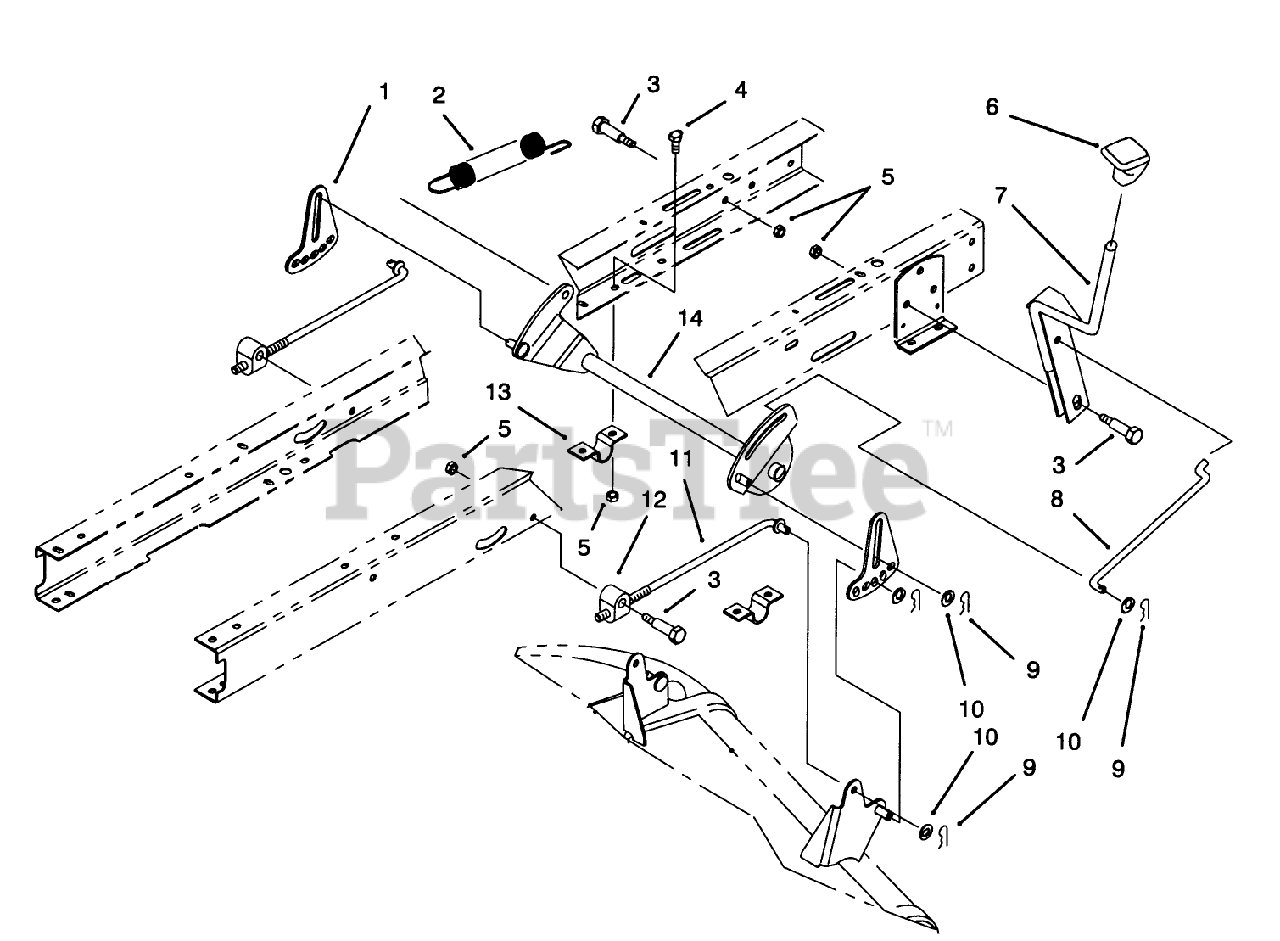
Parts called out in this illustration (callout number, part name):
2	SPRING-EXTENSION
3	SCREW-SHOULDER, HH
4	SCREW-HH
5	NUT-LOCK, NI
6	SHIFT KNOB
8	LINK-HOC
10	WASHER-FLAT
11	ROD-HANGER, REAR
12	TRUNNION-HOC
13	CLAMP-PIVOT, HOC
